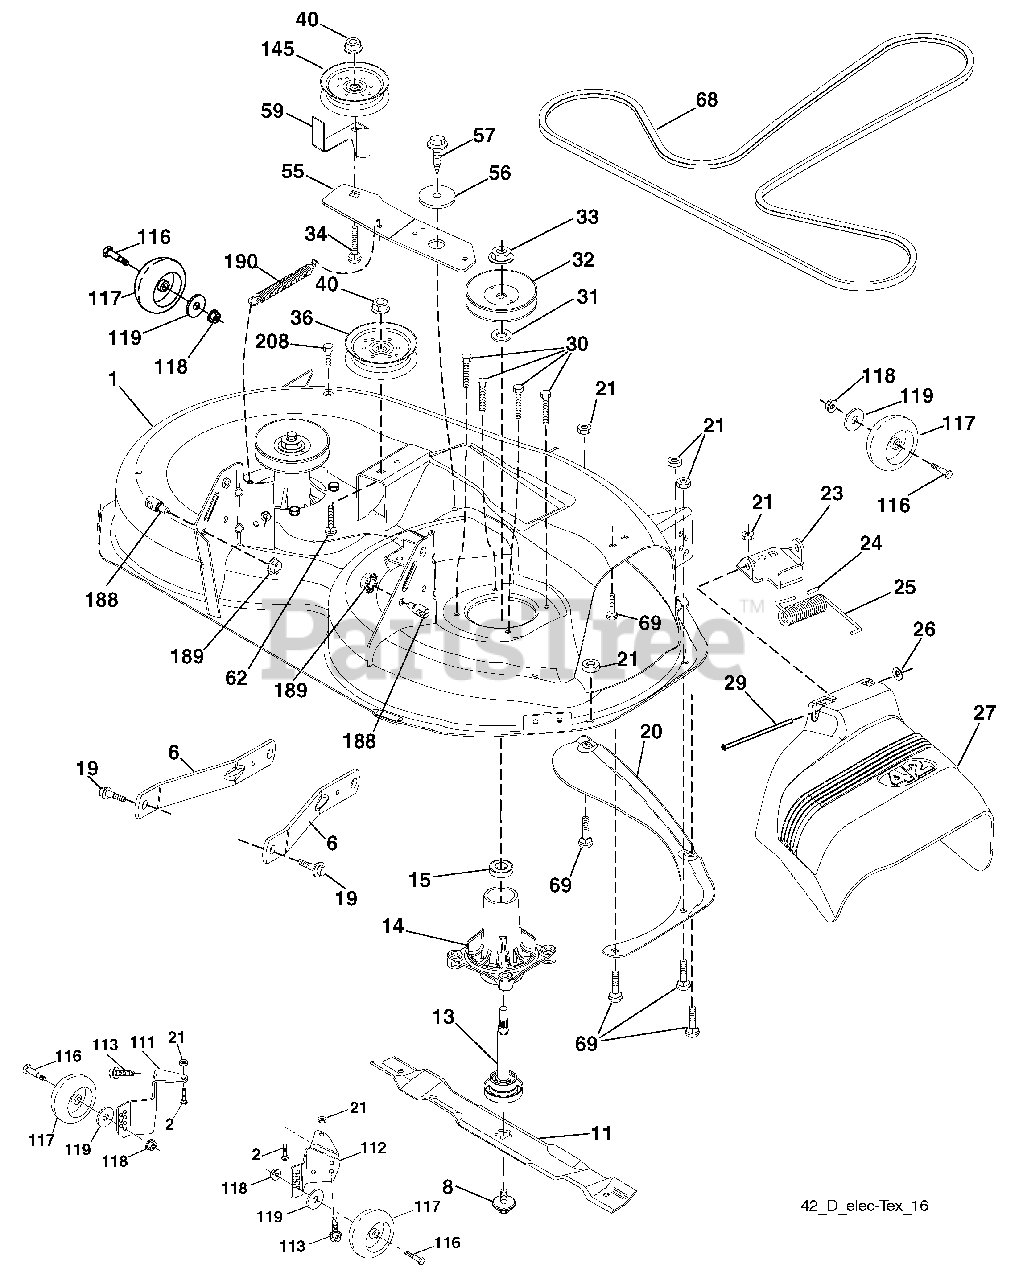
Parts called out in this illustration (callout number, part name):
1	Mower Housing
2	Bolt RDHD SQNK 5/16-18 unc x 3/4
6	Arm Suspension
8	Bolt/Washer Asm 7/16-20 unf
11	Blade, 42" Hi-Lift (For bagging or discharge)
13	Shaft Assembly, Mandrel
14	Housing, Mandrel
15	Bearing, Ball, Mandrel
19	Bolt, Shoulder
20	Baffle, Vortex
21	Nut, Crownlock 5/16-18 unc
23	Bracket, Deflector
24	Cap, Sleeve
25	Spring, Torsion, Deflector
27	Shield, Deflector
29	Rod, Hinge
30	Screw Thdrol Rolling Wsh Hd
31	Washer, Spacer
32	Pulley, Mandrel
33	Nut, Toplock, Flanged
34	Bolt Carr Sh. 3/8-16 x 1-1/2 Gr. 5
36	Pulley, Idler, Primary
40	Nut, Lock Flg. 3/8-16 unc
55	Arm, Idler
56	Spacer, Retainer
57	Screw 3/8-16 x 1
59	Guard, Tuv Idler
62	Bolt RDHD SQNK 3/8-16 x 2
69	Bolt
111	Bracket Wheel Gauge LH 42"
112	Bracket Wheel Gauge RH 42"
113	Bolt 5/16-18 Hex WHS HD LCKSERR
116	Bolt, Shoulder
117	Wheel, Gauge
118	Nut, Lock 3/8-16 unc
119	Washer 3/8 x 7/8 x 14 Ga.
145	Pulley Idler
188	Stud Fastener
189	Nut Lock Hex Flange
190	Spring Mower Drive
208	Screw THDROL 3/8-16 x 1/2
